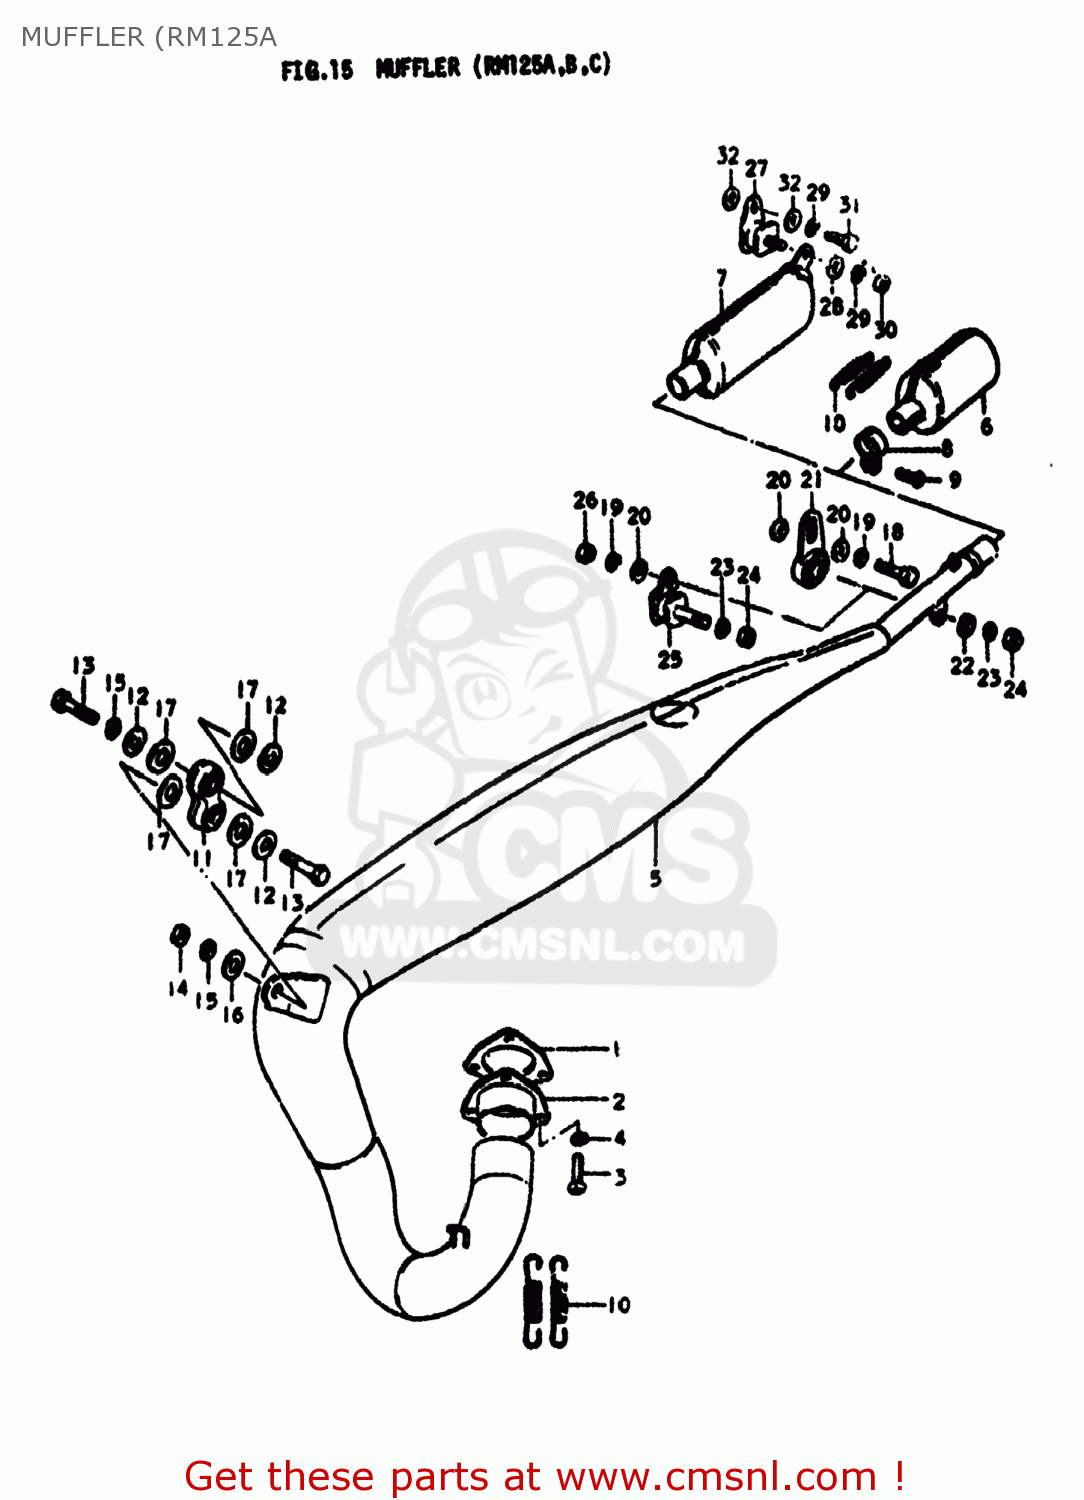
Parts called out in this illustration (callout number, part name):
1	GASKET,EXHAUST PIPE (MCA)
2	FLANGE,EXHAUST PIPE
3	SCREW
4	LOCK WASHER
5	BODY,MUFFLER
6	BODY,MUFFLER
7	BODY,MUFFLER
8	CLAMP
9	BOLT(6X20)
10	SPRING
11	DAMPER,MUFFLER
12	WASHER
13	BOLT
14	NUT
15	LOCK WASHER
16	WASHER
17	WASHER(13X28X1.6)
18	BOLT
19	LOCK WASHER
20	WASHER (8.5X29X1.6)
21	DAMPER,MUFFLER SUPPORT
22	WASHER
23	LOCK WASHER
24	NUT
25	DAMPER,MUFFLER SUPPORT
26	NUT
27	DAMPER,MUFFLER SUPPORT
28	WASHER
29	WASHER,LOCK,8.
30	NUT
31	BOLT
32	WASHER (8.2X20X1.6)
